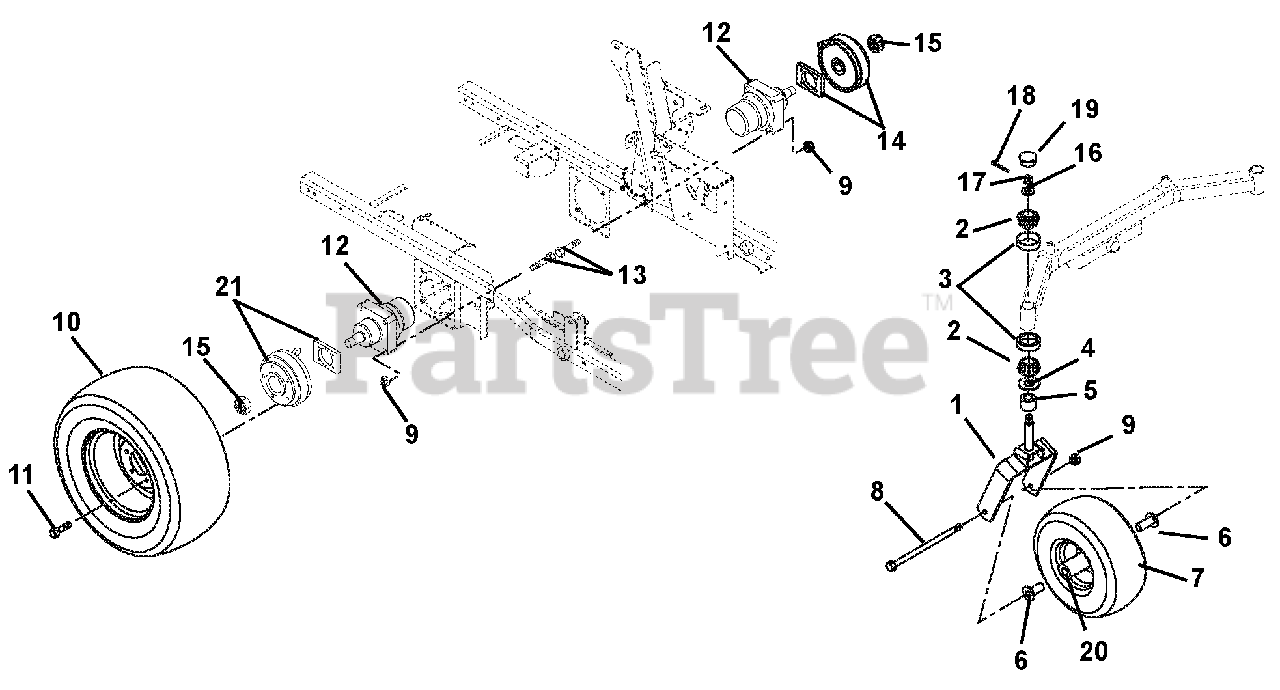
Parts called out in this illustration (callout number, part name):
1	Fork, Front
2	Bearing, Cone w/ Grease
3	Bearing, Cup 1.980 x .420
4	Bearing Seal 1.5 x 2 x .18
5	Spacer, PM, 1.03 I.D. x 1.5 O.D. x .375
6	Spacer, Wheel
7	Wheel/Tire Assembly
8	Bolt, Hex .50-13 x 9.00 Grade 5
9	Nut-Locking-Top-Flange .50-13
10	Tire/Wheel Assembly 24 x 12-12
11	Bolt, Lug .50-20 x 1.38 Grade 8, 60 Degree
12	Hydraulic Wheel Motor (includes 15)
13	Bolt, Wheel Motor .50-13 x 2.75
14	Brake, Right Hand Park
15	Nut, Lock Jam Patch (Included with 12)
16	Washer, Flat Steel .755 x 1.375 x .062
17	Nut, Slotted .75-16
18	Pin, Cotter .16 x 1.00
19	Cap, Dust
20	Bearing, 25mm I.D. x 52mm OD x 15mm
21	Brake, Left Hand Park
